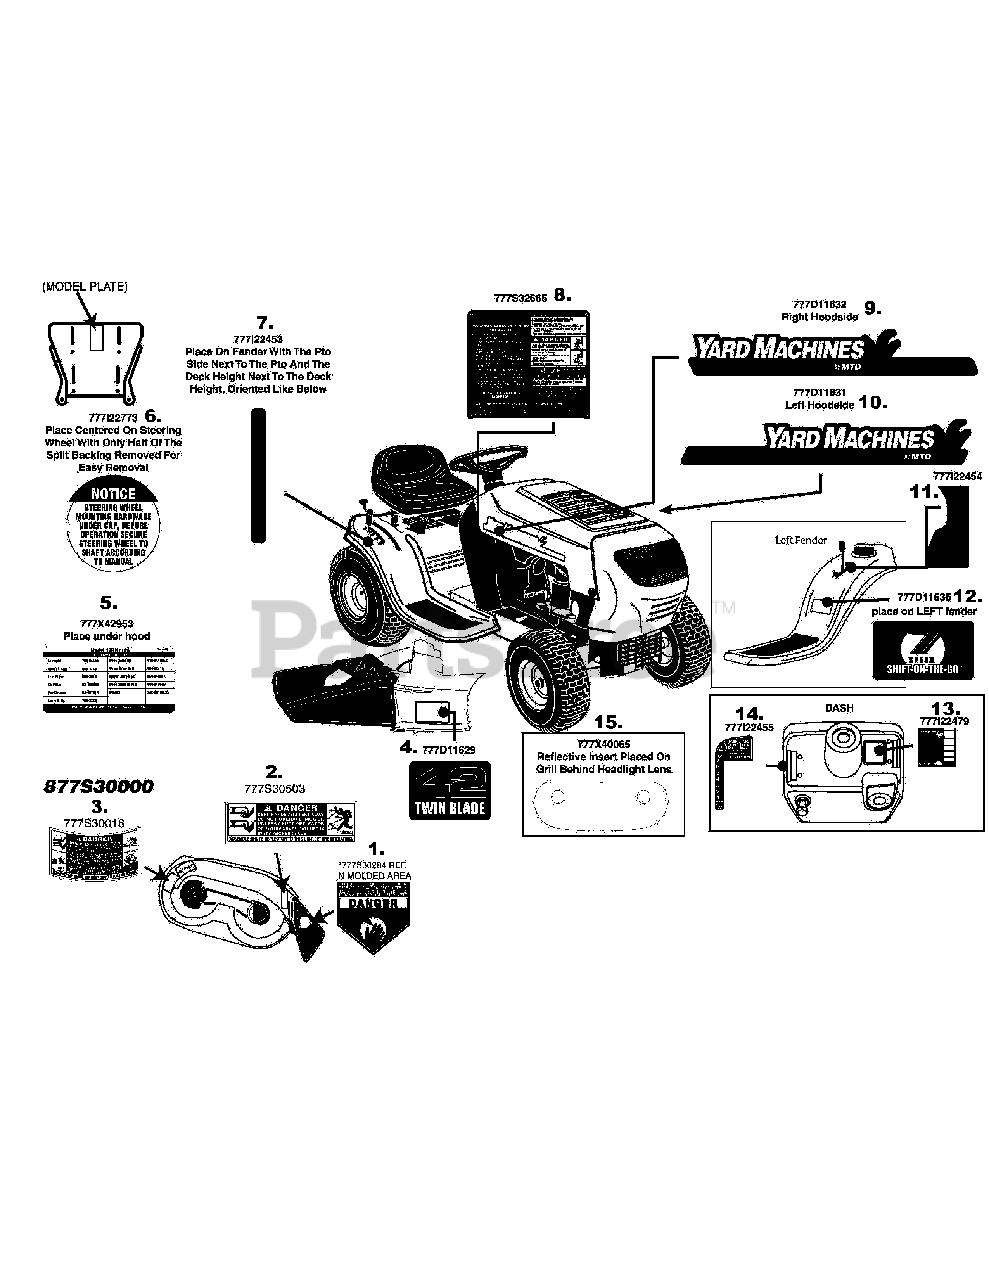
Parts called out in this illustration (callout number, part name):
1	LABEL
2	LABEL-DANGER CHUTE
3	LABEL-DECK SAFETY
4	LABEL-RIDER DECK YARD MACHINE 42"
5	LABEL-RIDER PARTS LIST
6	LABEL-RIDER:SECURE WHEEL
7	LABEL:RIDER LT-5 FENDER
8	LABEL:RIDER SAFETY TRANS
9	LABEL-RIDER HOOD RH YARD MACHINE
10	LABEL-RIDER HOOD LH YARD MACHINE
11	LABEL:RIDER LT-5 FENDER
12	LABEL-RIDER FENDER YARD MACHINE
13	LABEL: RIDER LT-5 THRT/CHK
14	LABEL:RIDER LT-5 DASH
15	LABEL REFLECTOR
